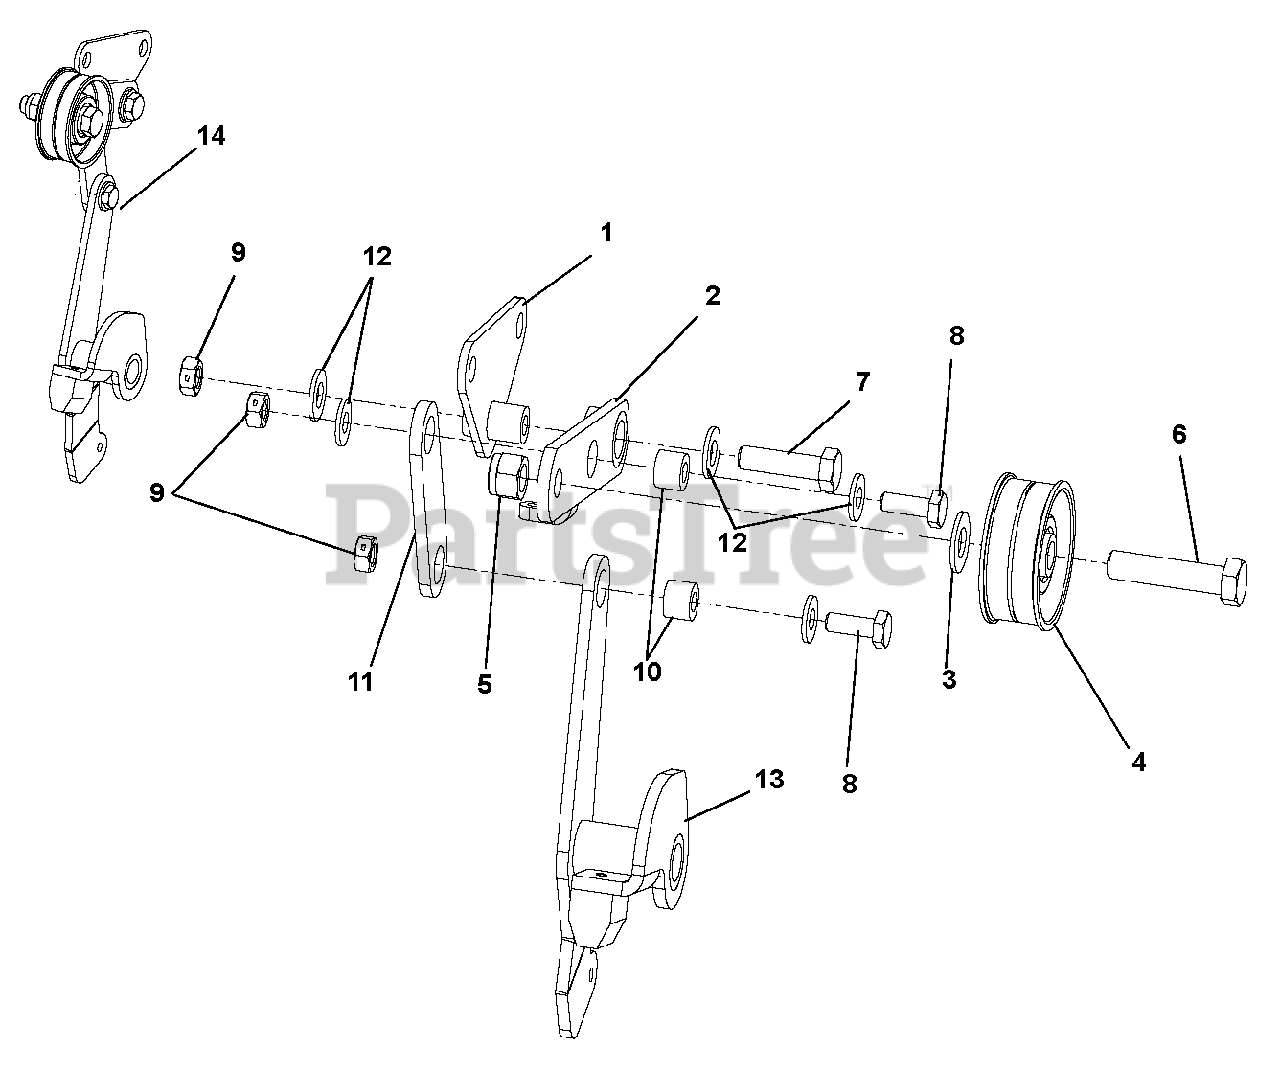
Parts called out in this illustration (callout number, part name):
1	Pivot Plate Weldment
2	Idler Arm Weldment
3	Washer, Flat Steel .406 x .812 x .065
4	Clutch Pulley 3/4
5	Locknut, Nylock 3/8-16
6	Bolt, Hex .38-16 x 1.75
7	Bolt, Hex .31-18 x 1.25 Grade 5
8	Bolt, Hex .25-20 x .75 Grade 5
9	Nut, Locking Center .25-20
11	Link, Dethatcher
12	Washer, Flat .250 x .625 x .065
13	Brake Lever W/Pad
14	Clutch Pulley Assembly
